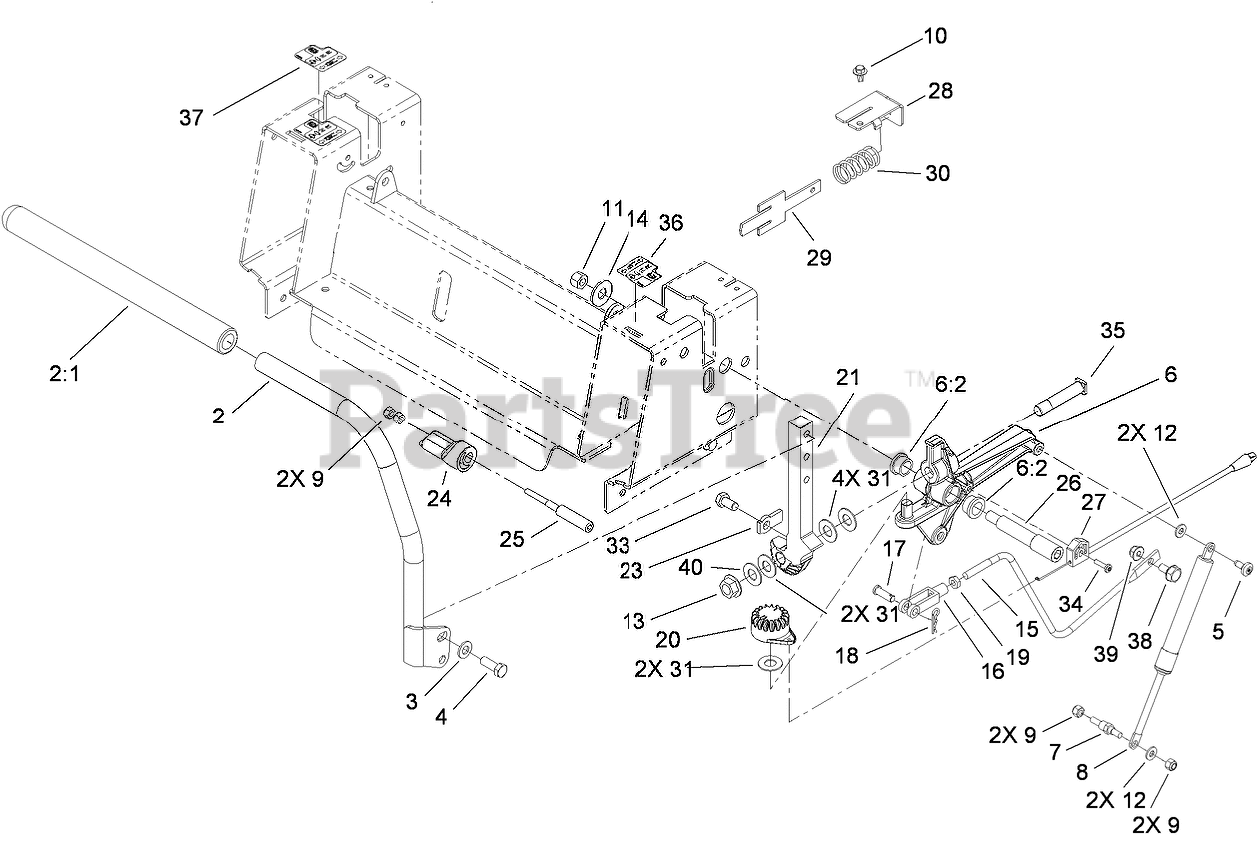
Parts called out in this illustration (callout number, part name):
2	LH HANDLE ASM
3	WASHER-FLAT
4	SCREW-HH
5	SCREW-SHOULDER
6	ACTIVATOR ARM ASM
6:2	BUSHING
7	STUD-DAMPER
8	Damper-Control, Motion
9	NUT-LOCK, NI
10	SCREW-HHFTF
11	NUT-LOCK, NI
12	WASHER-FLAT
13	NUT-HF
14	WASHER-FLAT
15	LINK-HYDRO
16	YOKE-ADJUSTABLE
17	PIN-CLEVIS
18	PIN-COTTER
19	NUT-JAM
20	GEAR-CONTROL
21	ARM-ACTUATOR, LH
23	TAB-STOP
24	ECCENTRIC
25	SCREW-ECCENTRIC
26	BOLT-SHOULDER
27	CABLE-BRAKE, PARKING
28	BRACKET-RETURN
29	PLATE-RETURN
30	SPRING-COMPRESSION
31	WASHER-PIVOT
33	SCREW-HH
34	SCREW-TORX
35	BOLT-SHOULDER
36	DECAL-CONTROL LEVER, LH
37	DECAL-CONTROL LEVER, RH
38	BOLT-SHOULDER
39	NUT-HF, NI
40	WASHER-TEFLON
